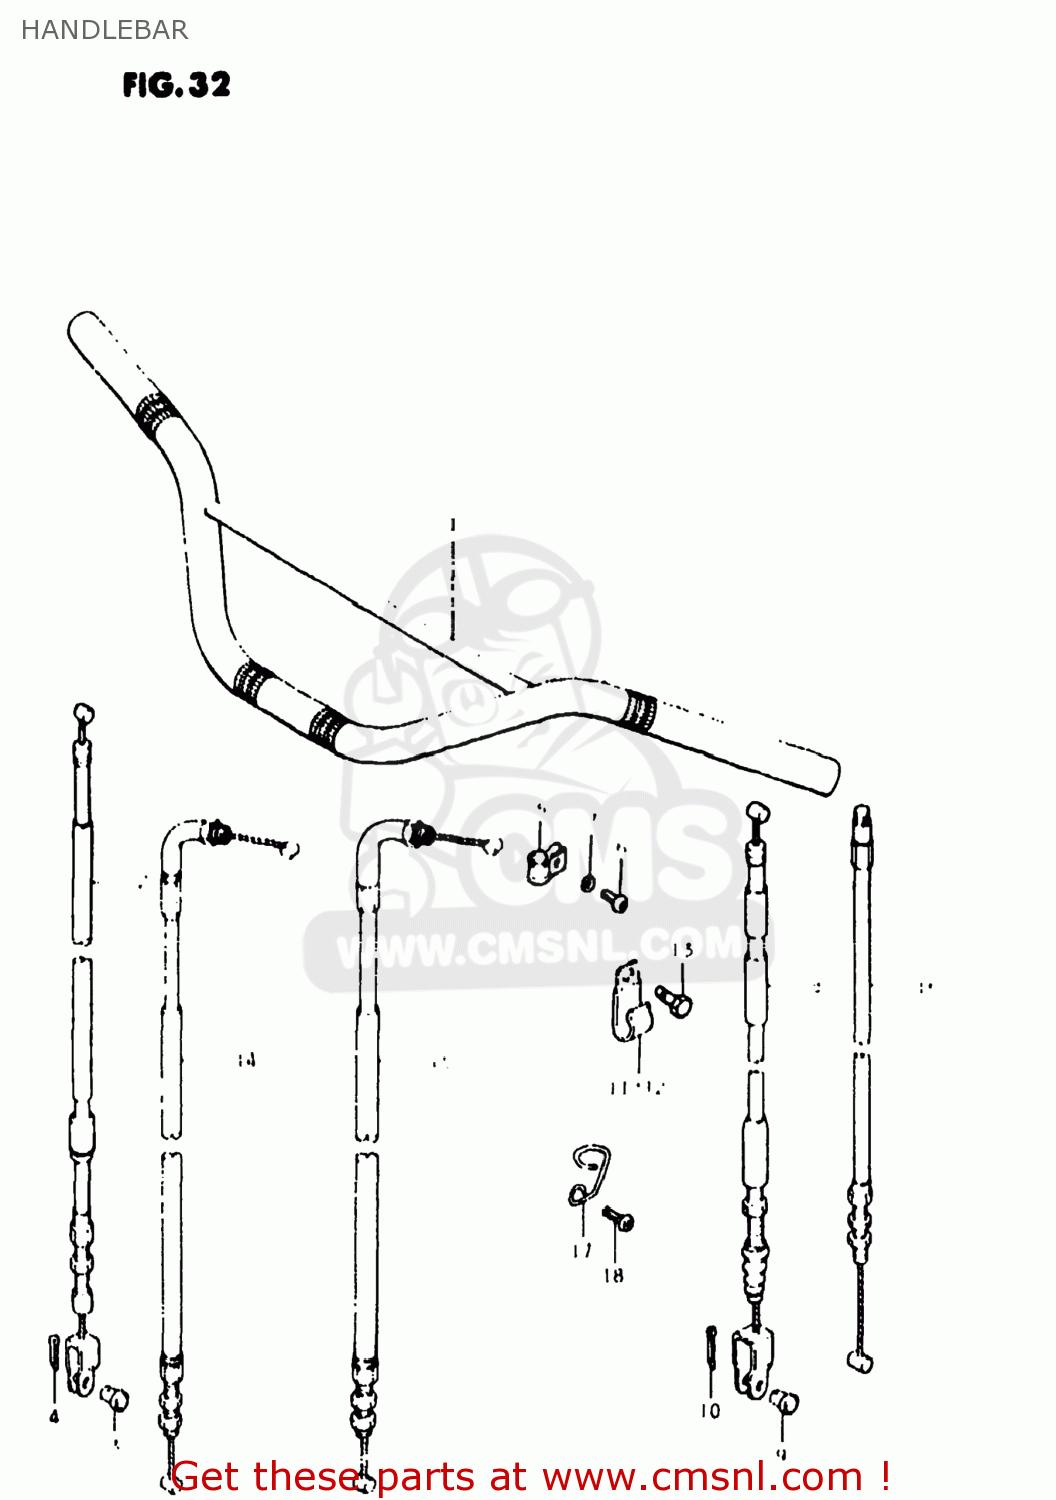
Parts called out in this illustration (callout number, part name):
1	HANDLEBAR
2	CABLE ASSEMBLY,FRONT BRAKE
3	PIN(L:17.5)
4	PIN
5	GUIDE,CABLE
6	SCREW
7	LOCK WASHER
8	CABLE ASSEMBLY,CLUTCH
9	PIN(L:15)
10	PIN
11	CLAMP
12	CLAMP
13	BOLT
14	CABLE ASSEMBLY,THROTTLE NO
15	CABLE ASSEMBLY,THROTTLE NO
16	CABLE ASSEMBLY,DECOMPRESSION
17	GUIDE
18	SCREW
